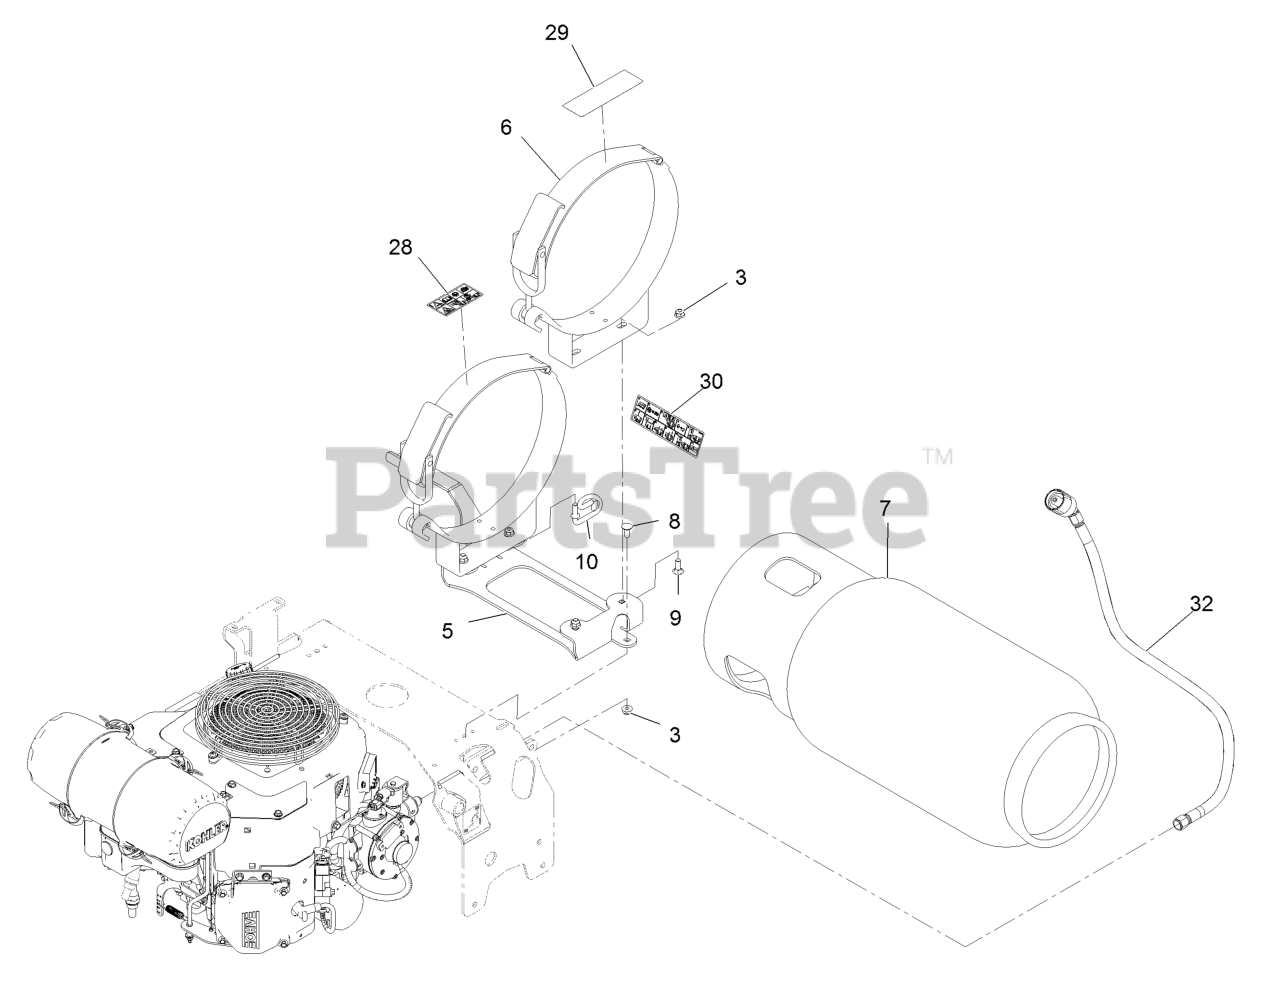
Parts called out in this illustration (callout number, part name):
3	Nut-Nyloc 5/16-18 Flg
5	Weld, Tank Mount
6	Brackets, LPG Tank - Horizontal (Pair)
7	Tank, LP - 33.5 Lb.Horizontal-Al
8	Bolt-Carriage 5/16-18 X 3/4 Short Neck
9	Bolt-Carriage 5/16-18 X 7/8
10	Retainer, LP Hose
28	Decal-LPG Warning
29	Decal-LPG Horiz Tank Spec
30	Decal-LPG Fuel Tank Replacement
32	ASM, LPG Hose W/Connector-Tt
